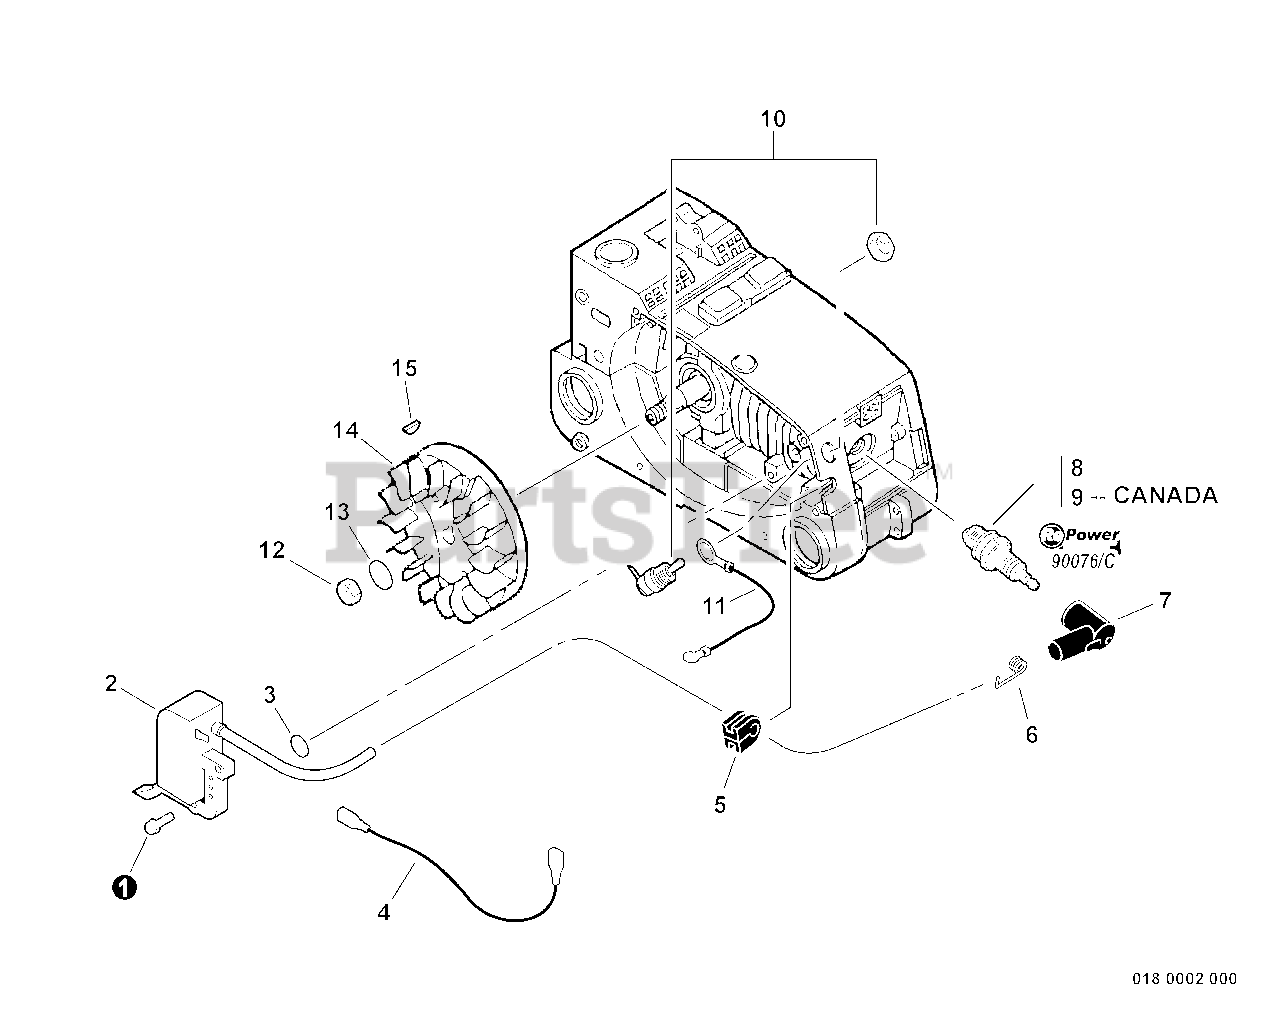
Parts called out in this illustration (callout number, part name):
1	SCREW 5×22
2	COIL, IGNITION
3	WASHER 5.2×12×3
4	LEAD - IGNITION L= 95
6	TERMINAL, SPARK PLUG
7	CAP, SPARK PLUG
8	SPARK PLUG - BPM8Y
9	SPARK PLUG - BPMR8Y
10	SWITCH, ON-OFF
11	LEAD - GROUND L= 100
13	WASHER 8.5×16×1.2
14	FLYWHEEL
15	KEY, WOODRUFF
16	TUNE-UP KIT
